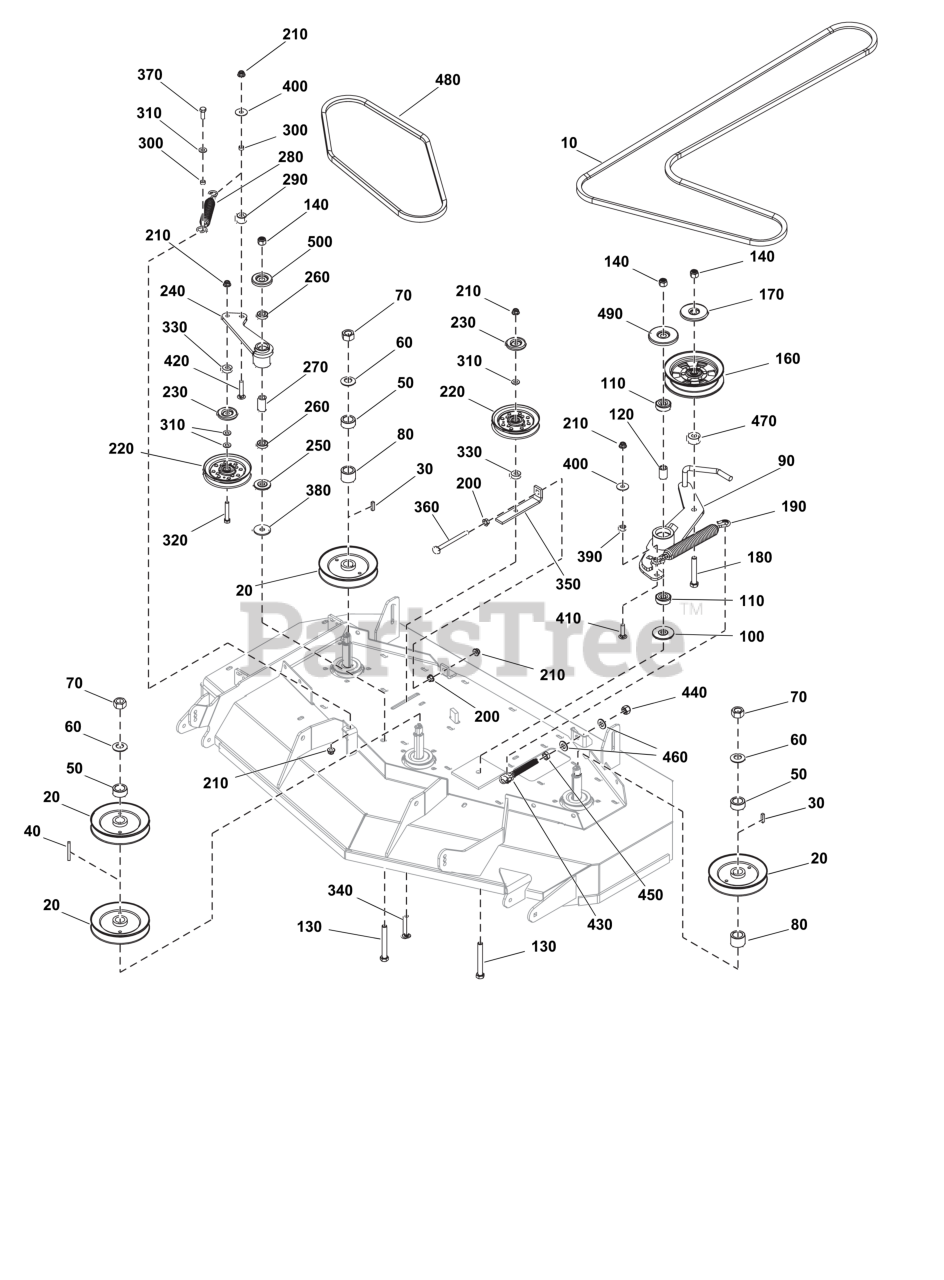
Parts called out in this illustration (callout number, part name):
30	KEY, 1/4" SQ. X 1.00
40	KEY - 1/4 SQX2 1/4
60	WASHER, Beveled
70	NUT, 3/4-16 HEX
90	ARM-IDLER
120	SPACER, .51 X .84 X 1
130	BOLT, 1/2-13 X 4 GD5
160	PULLEY, IDLER
180	BOLT, 1/2-13 X 2-3/4"
200	NUT, 3/8-16 HEX SERRA
210	NUT, 3/8-16 HEX NYLOCK
240	ARM-IDLER
250	SPACER, IDLER ARM
260	BEARING, BALL, AXLE
270	SPACER, .52 X .84 X 1
280	SPRING, EXTENSION, SW
300	SPACER, .38 X .50 X .
320	BOLT, 3/8-16 X 2-3/4"
370	BOLT, 3/8-16 X 1" GD5
400	WASHER, 3/8" FENDER
410	BOLT, 3/8-16 X 1-1/2
420	BOLT, 3/8-16 X 2", CA
430	ANCHOR, SPRING
440	NUT, 1/2-20 HEX NYLON
450	NUT, 1/2-20 HEX JAM
460	WASHER, 1/2" SAE
470	SPACER, .52 X 1.00 X
490	SHIELD, BEARING, 1/2" ID-2.5"
500	SHIELD, BEARING, 1/2" ID-1.75"
